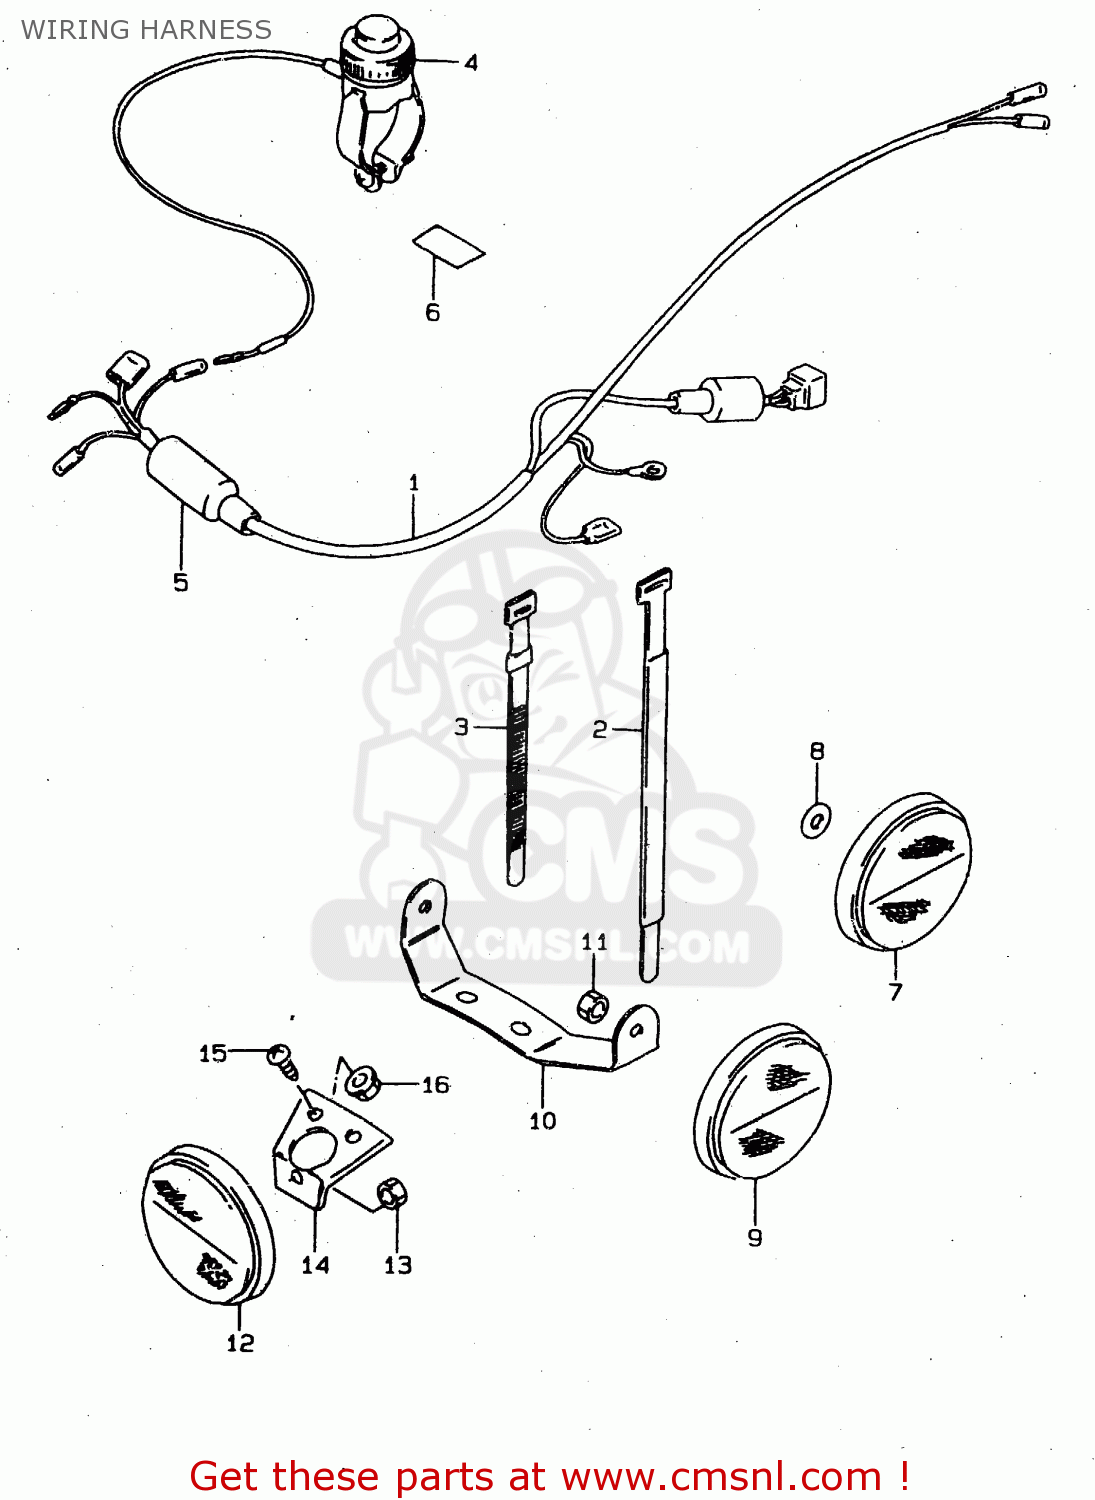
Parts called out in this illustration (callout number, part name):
1	HARNESS,WIRING
2	CLAMP(L:95)
3	CLAMP(L:120)
4	SWITCH ASSY,ENGINE STOP
5	COVER,WIRE
6	LABEL (ENGINE STOP)
7	REFLEX REFLECTOR,FR
8	WASHER
9	REFLEX REFLECTOR,RR
10	BRACKET,RR SIDE RR
11	NUT
12	REFLEX REFLECTOR,RR
13	NUT
14	BRACKET, REAR REFLECTOR
15	SCREW
16	NUT
